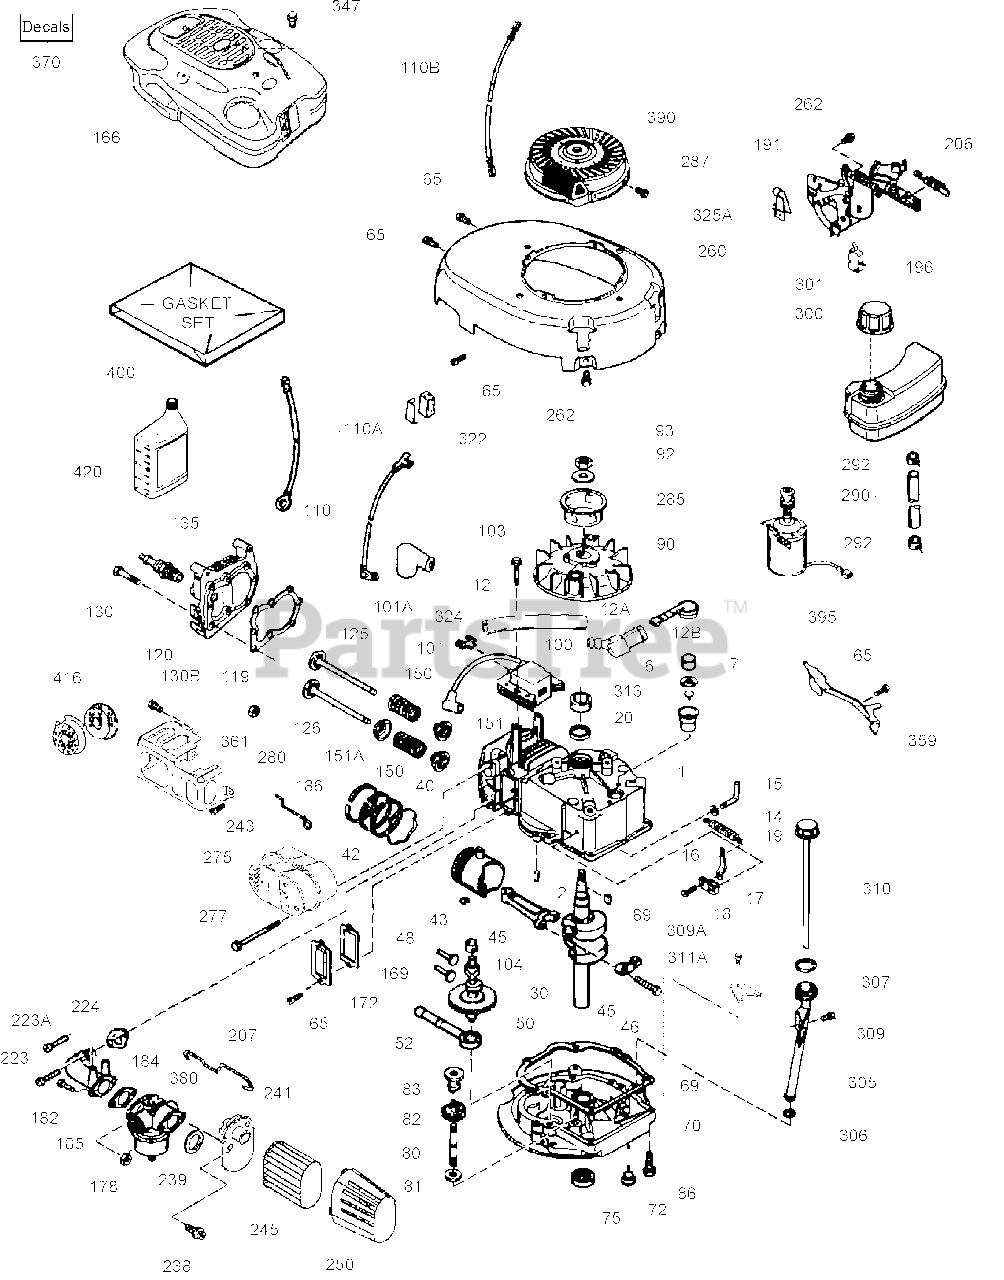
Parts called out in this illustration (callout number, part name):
166	Shroud-Engine (Green)
169	Gasket-Cover, Valve
172	Cover-Valve
178	Nut and Lock Washer (1/4-28)
182	Screw (1/4-28 x 7/8)
184	Gasket-Carburetor To Intake Pipe
185	Pipe-Intake
186	Link-Governor
191	Bracket-Brake (Includes 195)
196	Switch-Restart, Power
206	Terminal
207	Link-Throttle
223	Screw (1/4-20 x 1)
223A	Stud-Pipe, Intake
224	Gasket-Pipe, Intake
238	Screw (10-32 x 49/64)
239	Gasket-Air Cleaner
241	Collar-Air Cleaner
243	Screw (10-32 x 7/16)
245	Filter-Air Cleaner (also available in Packaged Part 740083)
250	Cover-Air Cleaner
260	Housing-Blower
262	Screw (1/4-20 x 1/2)
275	Muffler
277	Screw (1/4-20 x 2-9/32)
280	Shield-Heat
285	Cup-Starter
287	Screw (8-32 x 21/64)
290	Line-Fuel (Low Permeation)
292	Clamp-Line, Fuel
300	Fuel Tank ASM (Includes 292 and 301)
301	Cap-Fuel (Black) (1-1/2 ID) (also available in Packaged Part 740041B)
305	Tube-Fill, Oil
306	O-Ring
307	O-Ring
309	Screw (10-32 x 1/2)
309A	Screw (10-24 x 3/4)
310	Dipstick
311A	Bracket-Holddown
313	Spacer
322	Body-Connector
324	Terminal
325A	Clip-Actuator, Brake Switch
347	Screw (10-32 x 27/32)
359	Bracket-Control
361	Nut-Lock
370	Decal-Primer
370	Instruction Decal - Caution - read owner's manual
380	Carburetor ASM (Includes 184)
390	Starter-Recoil
395	12 Volt Electric Starter Motor ASM
400	Gasket Set
416	Spark Arrestor Kit (Includes 417)
420	Oil-Engine, SAE 30 (4-Cycle)
